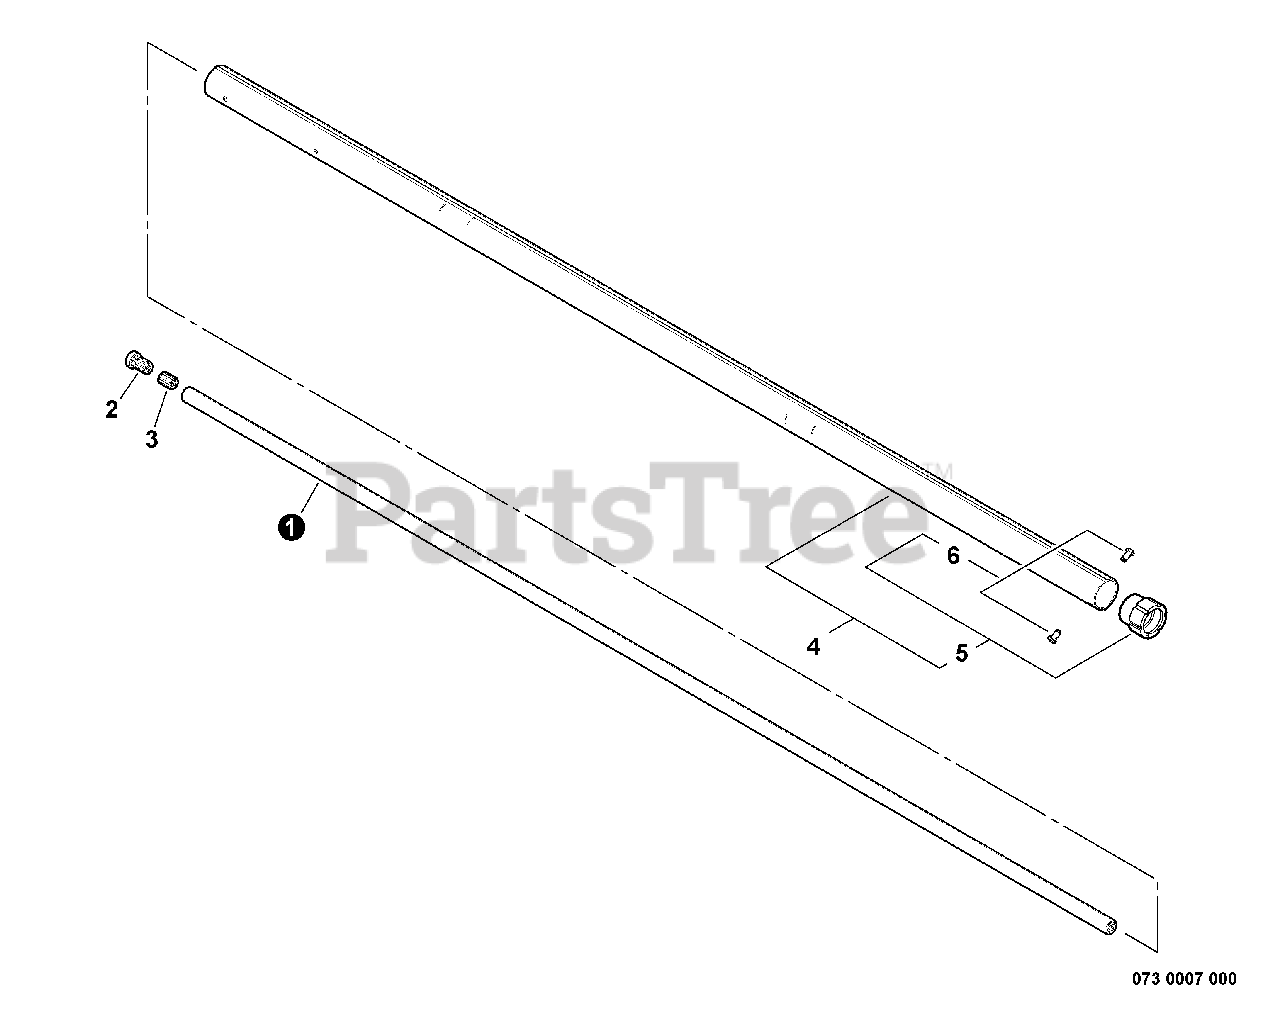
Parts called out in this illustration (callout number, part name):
1	DRIVESHAFT - UPPER
2	SOCKET - OUTER
3	SOCKET - INNER
4	MAIN PIPE ASSY - BLACK
5	HOLDER ASSY, BEARING
